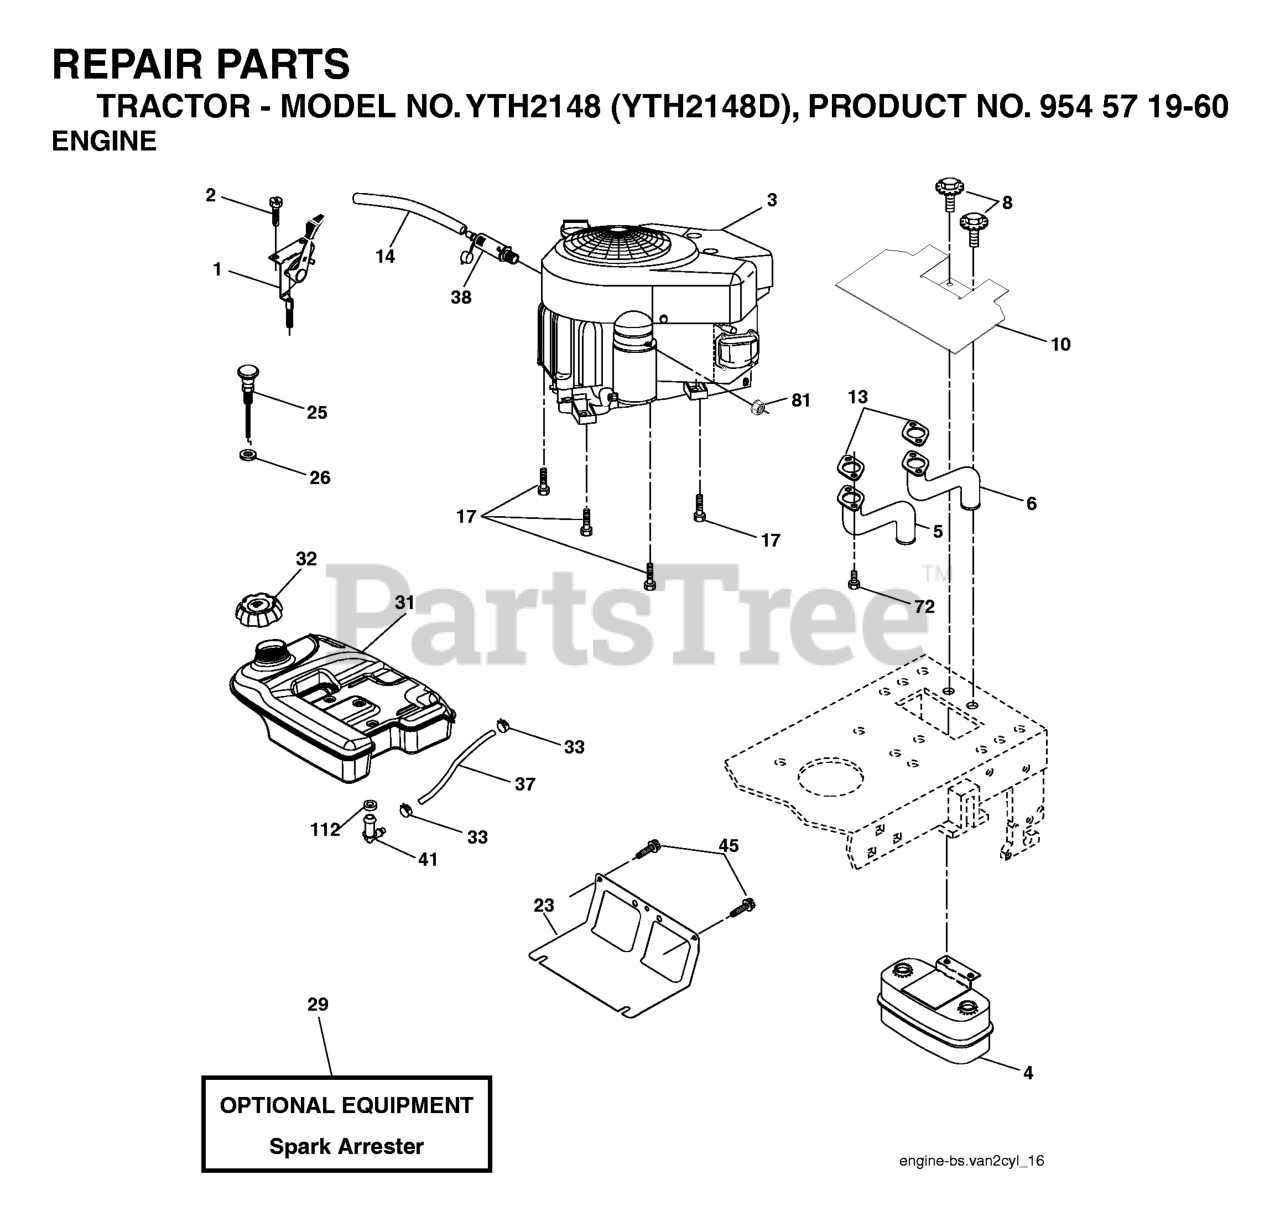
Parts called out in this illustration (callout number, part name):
1	CONTROL, THROTTLE
2	SCREW
4	MUFFLER.TWIN.CYL.LOW.TONE
8	BOLT.5/16-18UNCX3/4 W/SEMS.BLK
10	RP SHIELD HEAT MUFFLER
13	GASKET.MUFFLER
14	TUBE, DRAIN OIL ASM.
17	SCREW 3/8-16 X 1-1/2
23	SHIELD.BROWNING.DBR.GUARD
26	Nut Keps 3/8 - 24 UNF
29	KIT.SPARK ARRESTOR 794945 B&S
31	4.0 REAR FUEL TANK
32	TANK CAP
33	HOSE CLAMP
37	REPL BY 532 00 85-43
38	PLUG DRAIN OIL EASY
41	STEM FUEL TANK
45	SCREW, 3/8-16X3/4
72	SCREW.SOCKET.HEAD.5/16-18
81	NUT
112	BUSHING OUTLET T
